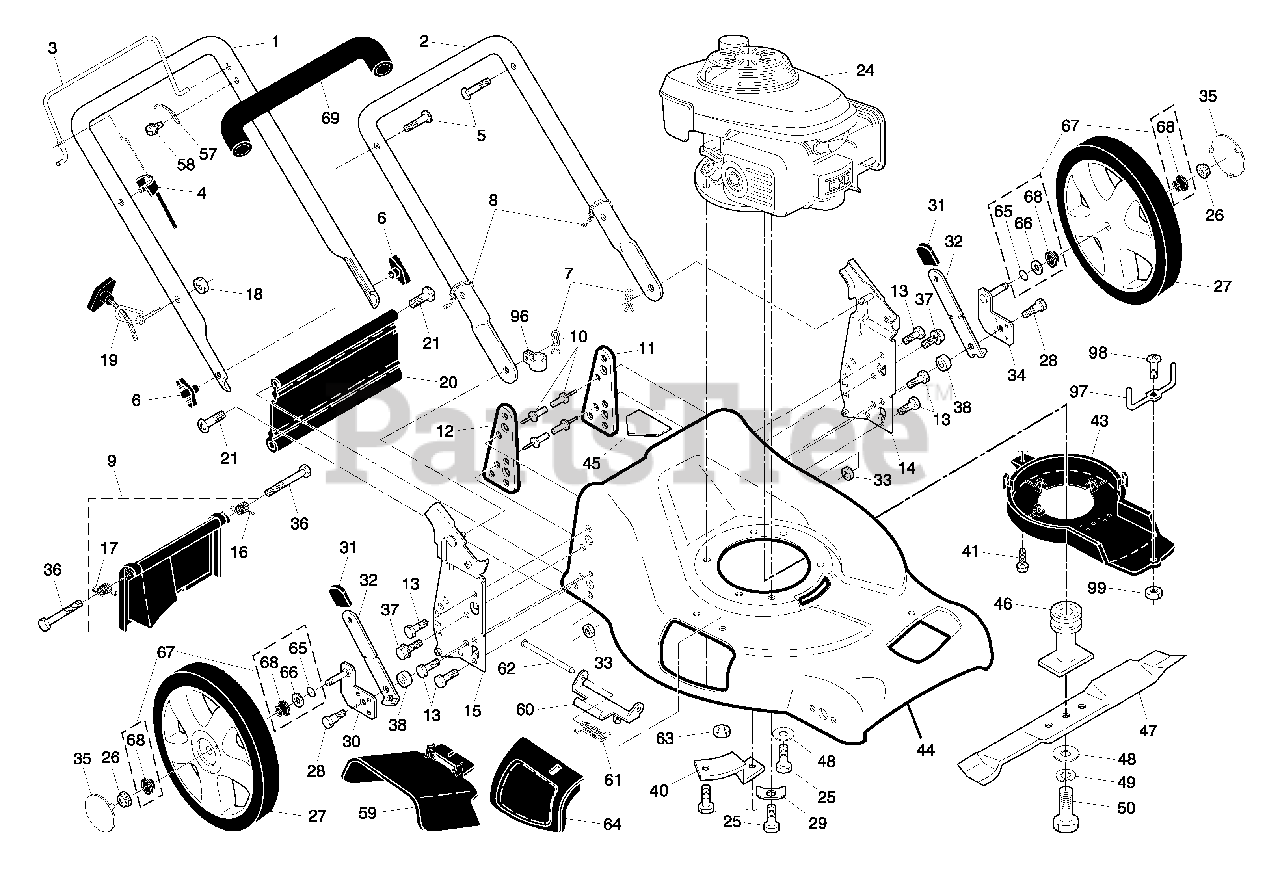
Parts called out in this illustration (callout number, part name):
1	Upper Handle
2	Lower Handle
3	Control Bar
4	Engine Zone Control Cable
5	Handle Bolt
6	Handle Knob
7	Hairpin Cotter
8	Wire Tie
9	Kit, Rear Door
11	Support Bracket, LH
12	Support Bracket, RH
13	Screw 1/4-20 x 5/8
14	Handle Bracket Assembly, LH
15	Handle Bracket Assembly, RH
16	Spring, LH
17	Spring, RH
18	Keps Locknut 1/4-20
19	Rope Guide
20	Rear Skirt
21	Screw, Tapping 1/4-20 x 1/2
25	Hex Head Thread Rolling Screw 3/8-16 x 1-1/8
26	Hex Flange Nut
27	Wheel & Tire Assembly, Rear, 14"
28	Shoulder Bolt 5/16-18 x .33
29	Washer, Engine, Zinc-Plated
30	Axle Arm Assembly, Rear, RH
31	Selector Knob
32	Selector Spring
33	Nut, Hex 5/16-18
34	Axle Arm Assembly, Rear, LH
35	Hubcap
37	Thread Cutting Screw w/Sems 5/16-18 x 3/4
40	Mounting Bracket, Debris Shield
43	Debris Shield
44	Kit, Lawn Mower Housing
45	Danger Decal
46	Blade Adapter / Pulley
47	Blade, 21"
48	Hardened Washer
49	Helical Washer 3/8-24 x 1-3/8 Grade 8
50	Hex Head Machine Screw 3/8-24 x 1-3/8 Grade 8
57	Upstop Bracket
59	Discharge Defl ector
60	Hinge Bracket
63	Nut, Hex
64	Mulcher Door
65	O-Ring
66	Washer, Flat 1/2
67	Kit, Bushing
68	Bushing, Nylon, Black
69	Grip, Foam
97	Belt Keeper
